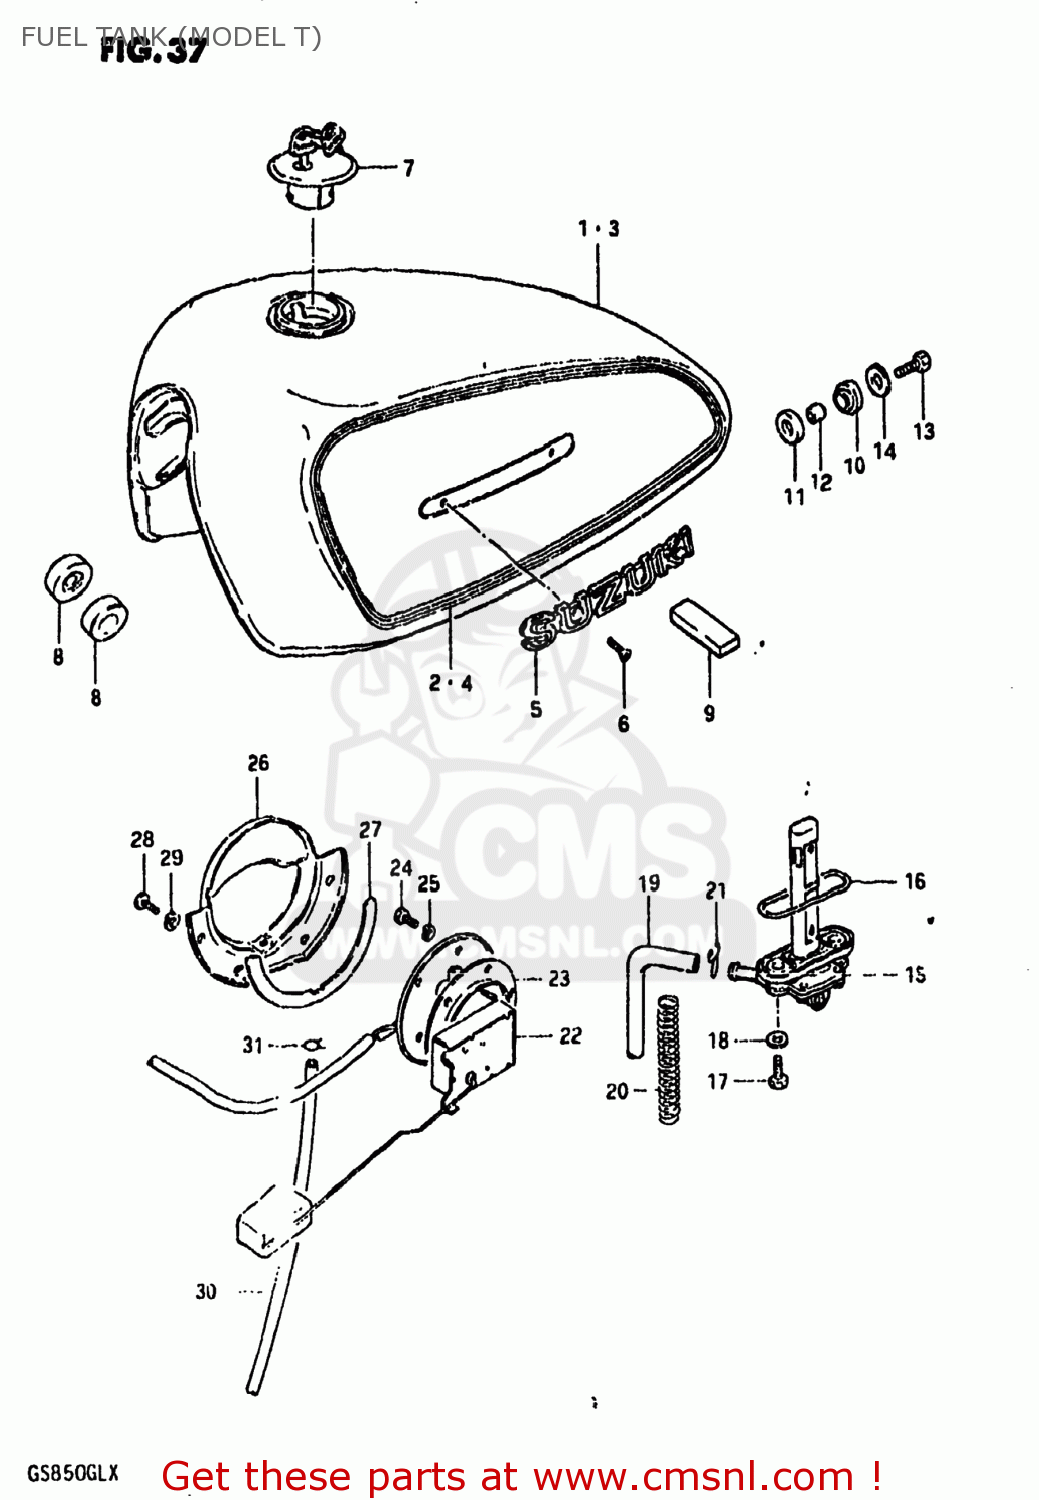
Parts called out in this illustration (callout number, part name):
1	TANK ASSEMBLY,FUEL
2	TAPE SET,FUEL TANK
3	TANK ASSEMBLY,FUEL
4	TAPE SET,FUEL TANK
5	EMBLEM
6	SCREW 3X6
7	CAP SET,FUEL TANK
8	CUSHION
9	CUSHION
10	CUSHION
11	CUSHION
12	SPACER(8.5X12X19)
13	BOLT (8X30)
14	WASHER (8.5X29X1.6)
15	COCK ASSY,FUEL
16	GASKET (NAS)
17	SCREW (6X25)
18	GASKET
19	HOSE
20	SPRING
21	CLIP
22	GAUGE ASSEMBLY,FUEL LEVEL
23	GASKET,FUEL LEVEL GAUGE (NAS)
24	BOLT
25	LOCK WASHER
26	PLATE,FUEL DRAIN
27	GASKET,FUEL DRAIN PLATE (NAS)
28	SCREW
29	LOCK WASHER
30	HOSE,FUEL
31	CLIP
